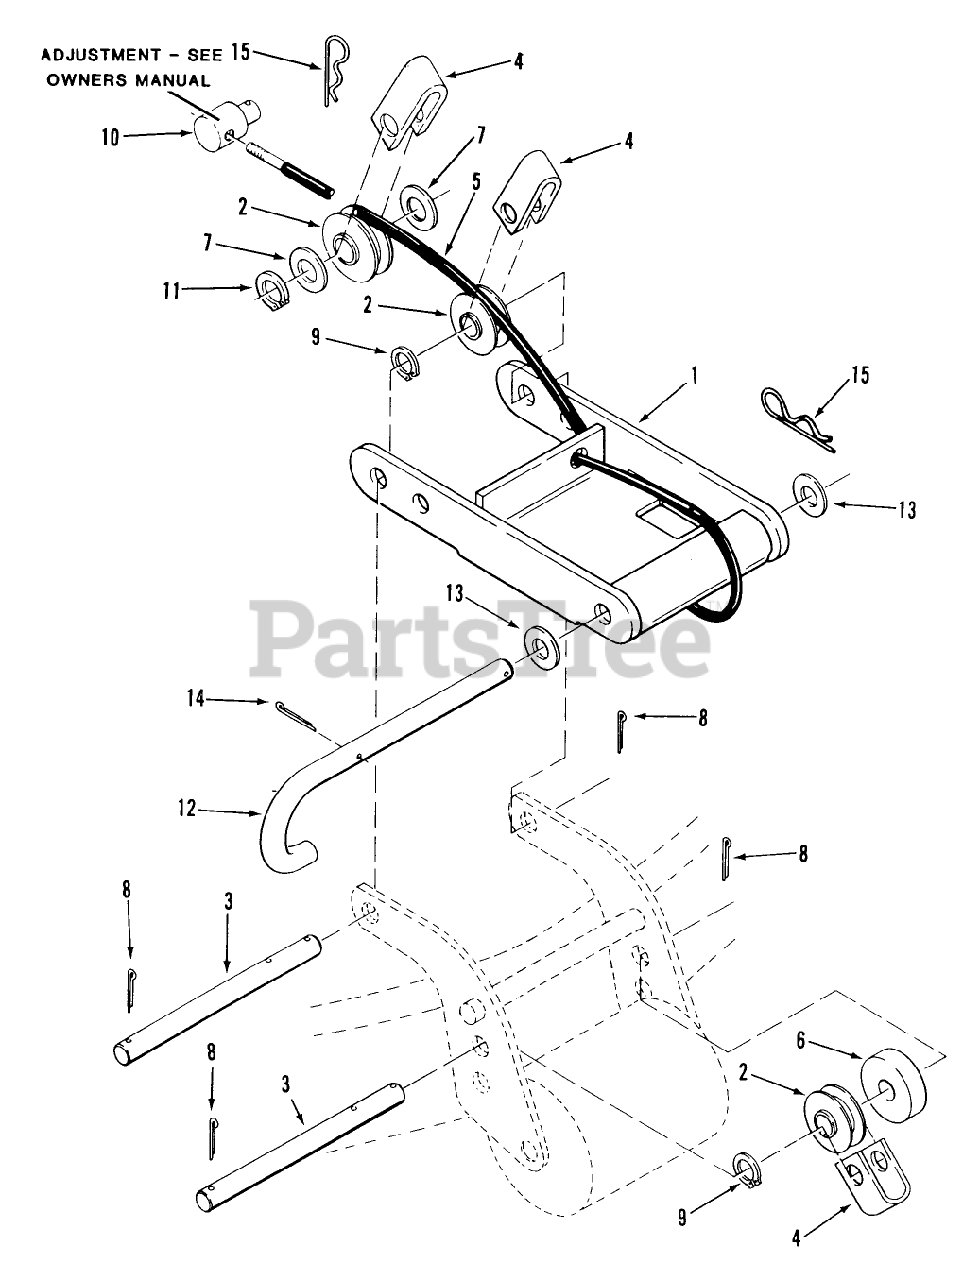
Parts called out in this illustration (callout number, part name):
3	ROD CABLE ROLLER
4	STRAP-CABLE
5	ASSY-CABLE
9	GRIP RING
11	GRIP RING
15	Hairpin Cotter
